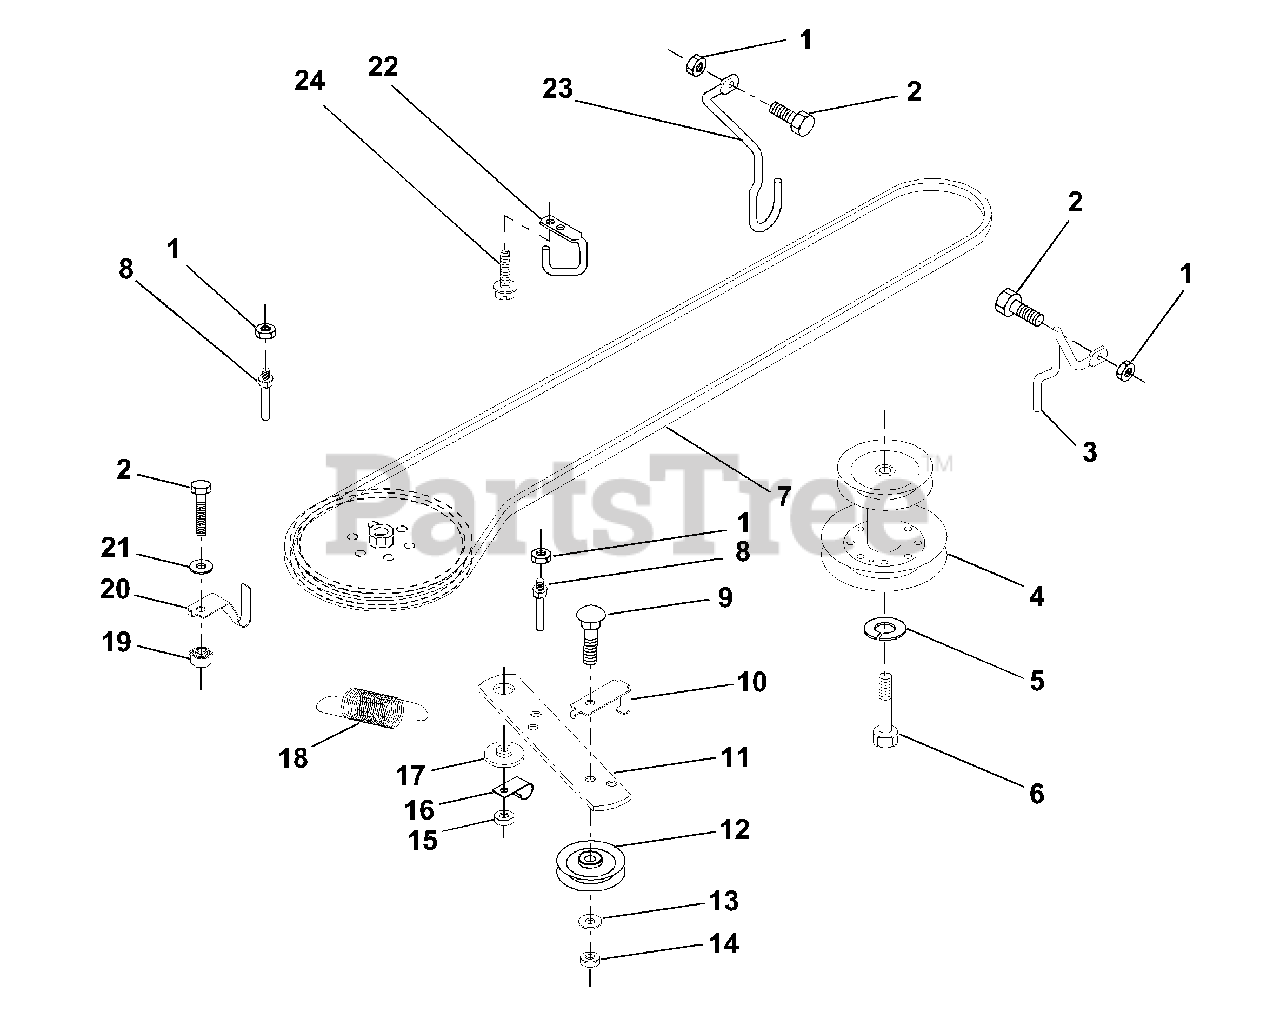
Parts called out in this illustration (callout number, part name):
1	Nut, Crownlock 5/16-18
2	Bolt, Hex Hd 5/16-18 UNC x 3/4
3	Keeper,Mower Drive, R. H.
4	Pulley, Engine
5	Washer, Lock 7/16
6	Bolt Hex 7/16-20 Gr. 5
7	Traction, V-Belt Drive
8	Keeper, T/A Ground Drive Belt
9	Bolt, Carr. 3/8-16 UNC x 1-1/2
10	Keeper, Belt Ground Drive Idler
11	Arm, Ground Drive Clutch
12	Idler, Flat
13	Washer 13/32 x 13/16 x 16 Ga.
14	Nut, Centerlock 3/8-16 UNC
15	Nut, Crownlock 3/8-16 UNC
16	Clip, Insulated
17	Spacer, Retainer
18	Spring Extension
19	Nut, Keps 5/16-18 UNC
20	Keeper, T/A Ground Drive Belt
21	Washer 11/32 x 5/8 x 16 Ga.
22	Keeper, Frame Ground Drive Belt
23	Keeper, Mower Drive, L. H.
24	Screw
